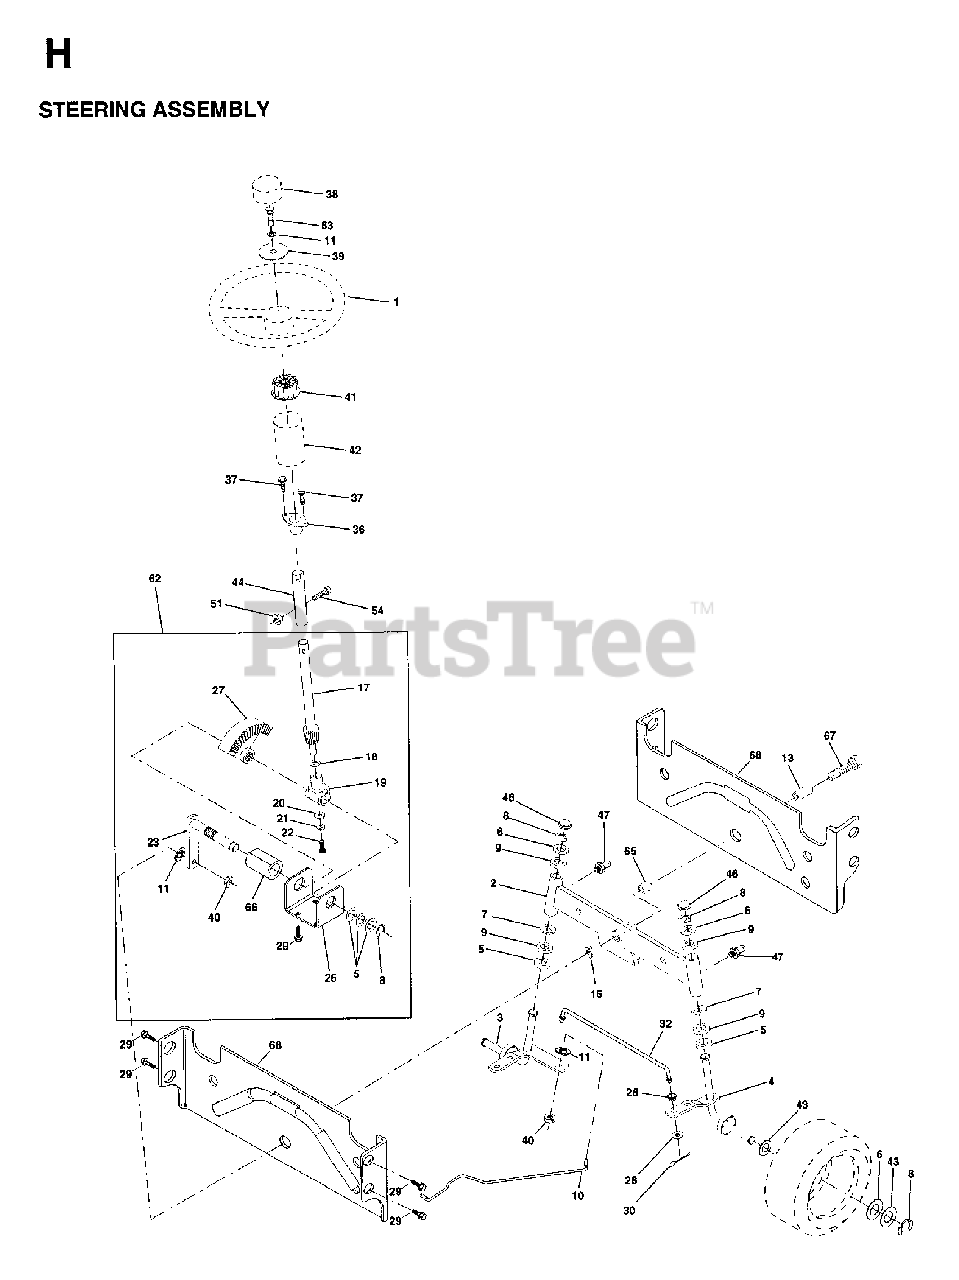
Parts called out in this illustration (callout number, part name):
2	AXLE ASSY
3	SPINDLE.ASM.LH
4	SPINDLE ASM, RH
8	RING CLIP
9	BRNG T
10	DRAGLINK-STAMPED
11	WASHER, LOCK 3/8
13	BEARING AXLE
15	NUT-LOC,FLANGE LT
17	SHAFT ASM STEERING
18	THRUST WASHER
19	SHAFT,SUPPORT
20	WASHER
21	LOCKWASHER
22	SCREW
23	PITMAN SHAFT ASSY
25	BRACKET STEERING
26	BUSHING.DRAGLINK
27	GEAR.SECTOR
28	WASHER
29	SCREW
30	COTTER PIN
32	TIE ROD
36	BUSHING, STEERING
38	RP INSERT
39	WASHER T
40	GRIPCO NUT
41	ADAPTER LT
42	STEERING BOOT, GRAY
44	EXT SHAFT STEERING
46	CAP.SPINDLE
47	ZERK M
51	NUT.71038.31-18.HEX.NYLOCK
54	BOLT.5/16-18X1-1/4 FULL.THREAD
62	KIT, STEERING ASSEMBLY
65	SPACER AXLE
66	BEARING ARM
67	BOLT.HEX.FINISHED.5/8
